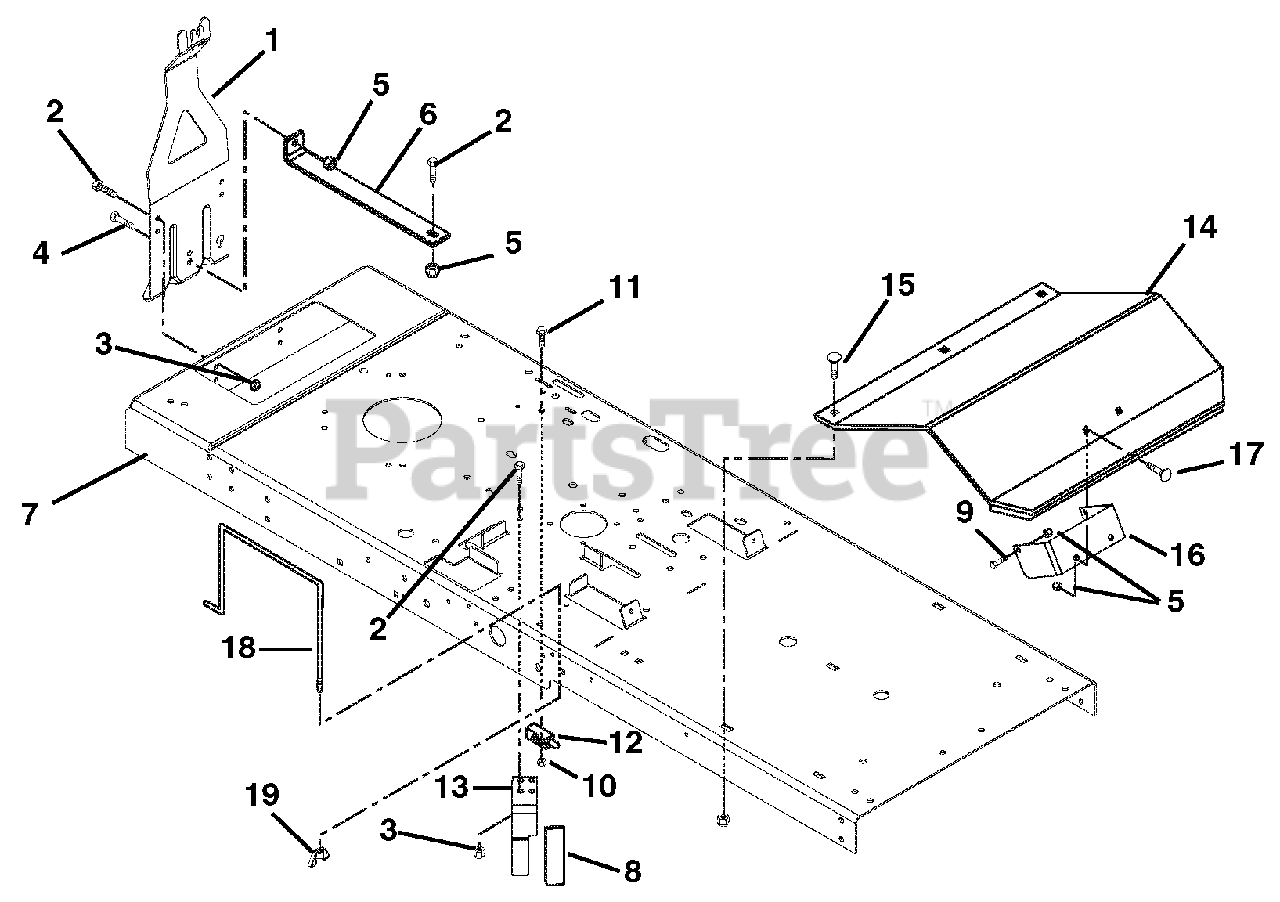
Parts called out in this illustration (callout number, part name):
1	Hitch-Trailer
2	Bolt Serrated Hex Flange Washer Head .31-18 x .62 Grade 5
3	Nut-Locking-Top-Flange .31-18
4	Bolt-Serrated Hex Flange Washer Head .375-16 x 1.00
5	Nut-Locking-Top-Flange .38-16
6	Brace
8	Grip
9	Bolt-Hex .25-20 x .75 Grade 5
10	Nut-Locking-Nylon 10-24 with Insert
11	Bolt-Hex 10-24 x .75 Flat Washer Head
12	Switch-Single Pole N.O.
13	Clutch Stop
15	Bolt-Round Head Square Neck .38-16 x .75 Grade 5
16	Bracket-Footrest
17	Bolt-Round Head Square Neck .25-20 x .50 Grade 5
18	Rod-Battery
19	Nut-Locking-Wing .250-20
